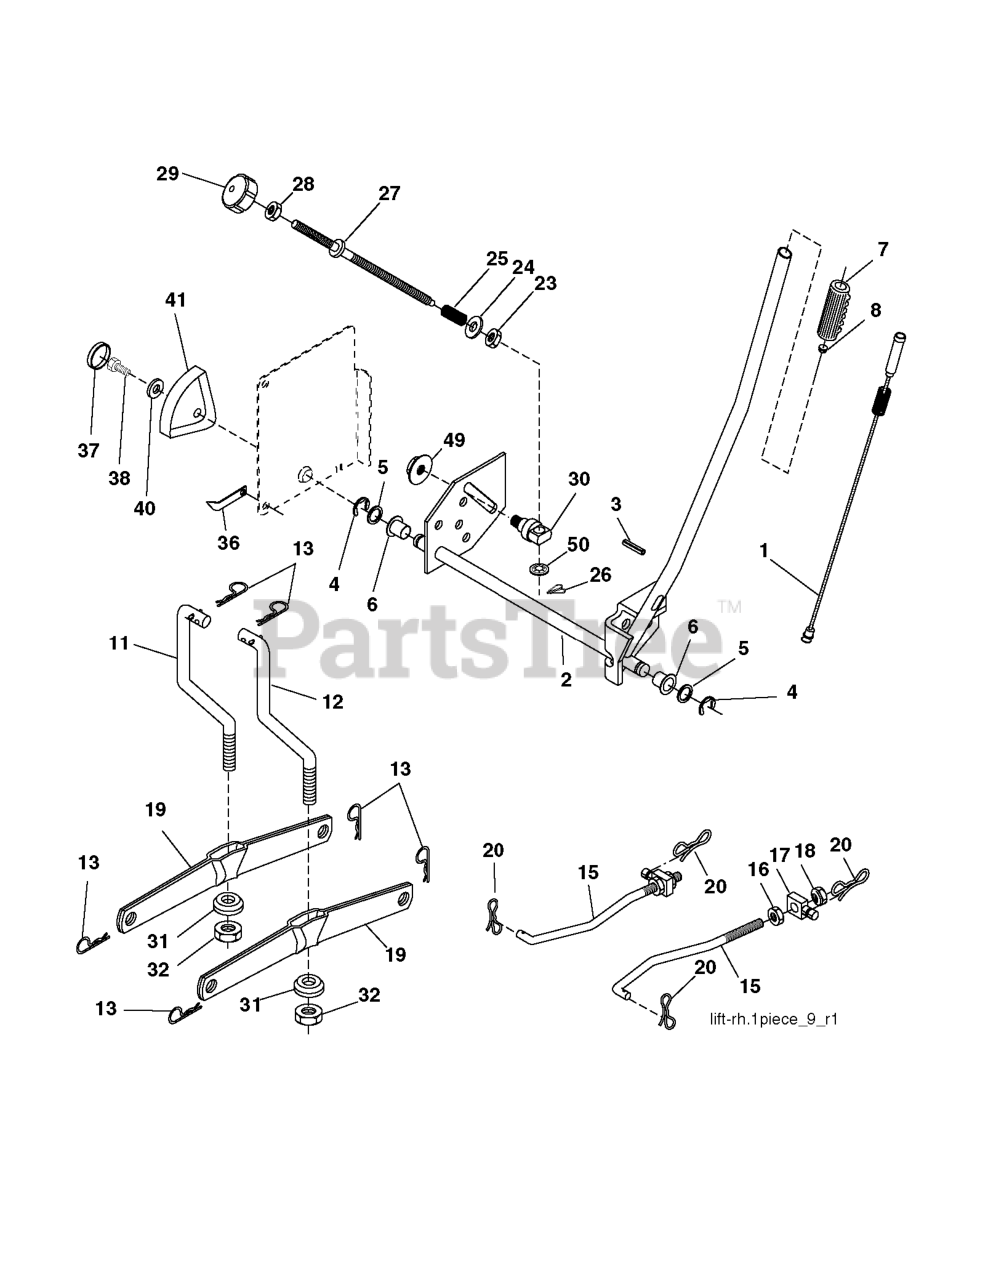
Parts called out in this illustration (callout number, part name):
1	WIRE ASM INNER W/ PLUNGER LT
2	SHAFT ASM R HANDLE
3	PIN GROOVE.
4	RETAINING RING LT
6	BEARING.NYLON
7	GRIP HANDLE
8	REPL BY 532 12 59-25
11	LINK
12	LINK
13	RETAINER-SPRNG RB
15	LINK.SUSPENSION.FRONT
16	NUT.HEX.JAM.1/2-13
18	NUT.LK.W/WSH.1/2.
19	ARM.REAR.SUSPENSION
20	PIN.COTTER.7/16.BOW TI.
26	RETAINER CLIP
27	ROD ADJ LIFT
28	NUT
29	KNOB INF 3/8-16
31	BEARING.PIVOT.LIFT
32	NUT CROWNLOCK 3/8-24
36	POINTER, HEIGHT INDICATOR(2 2)
38	SCREW 5/16-18X1
41	HEIGHT INDICATOR
49	NUT
50	NUT PUSH M
